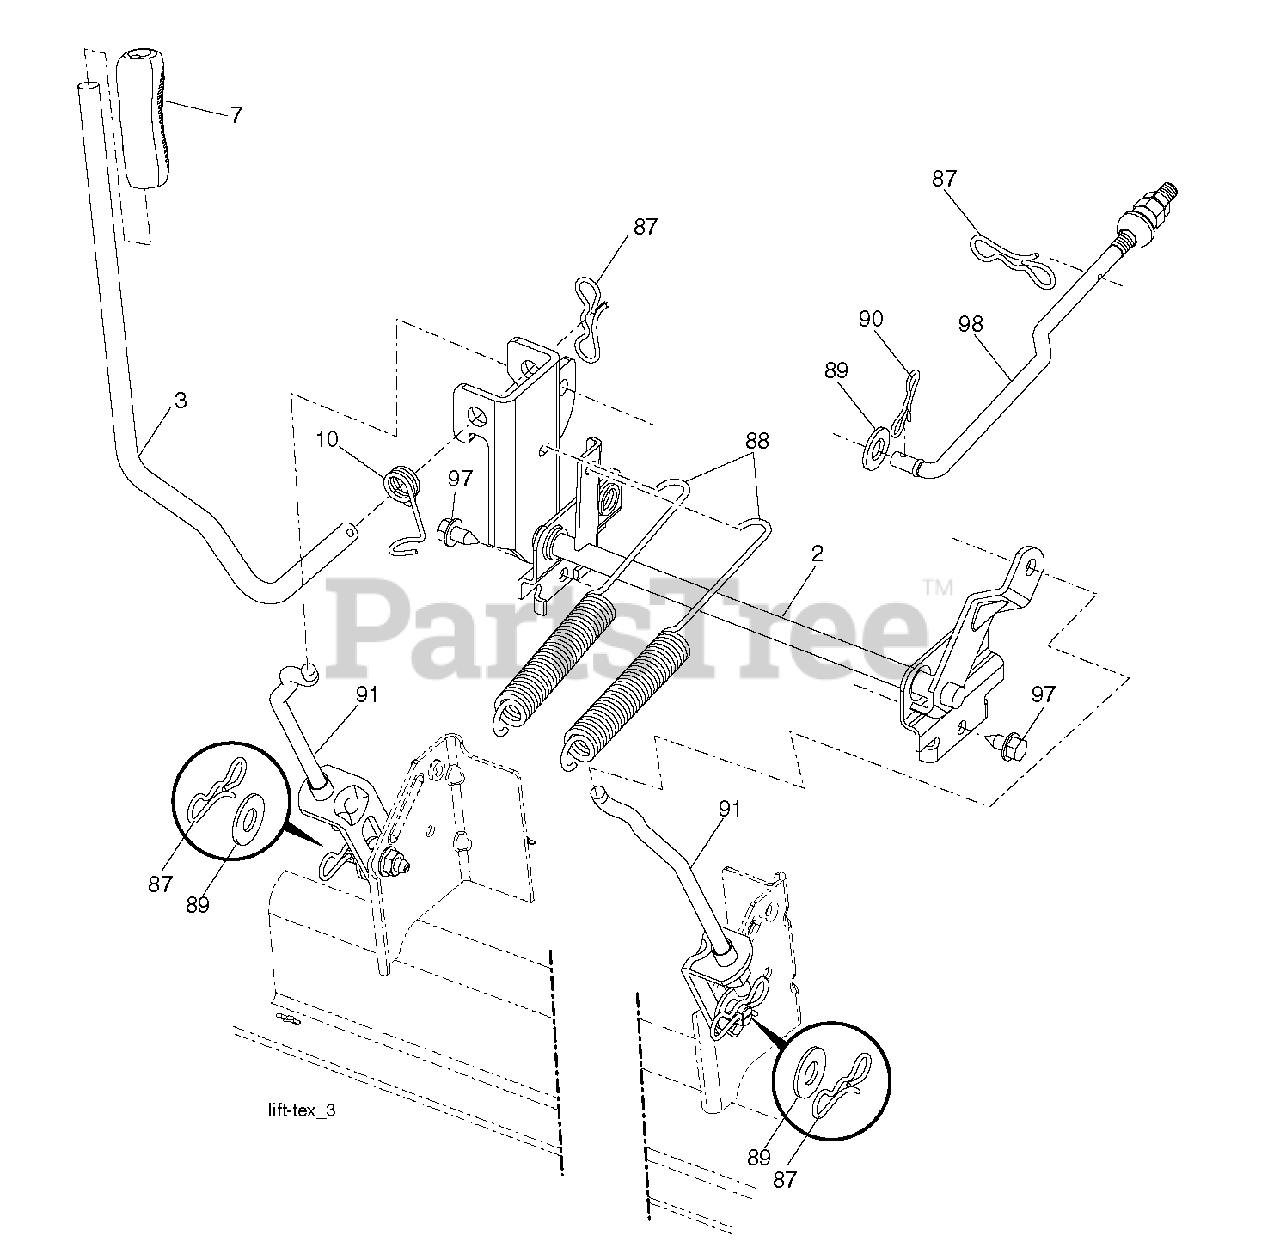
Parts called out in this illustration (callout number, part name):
2	SHAFT.ASM.CROSS.LIFT
3	LEVER.LIFT.HANDLE.LT
10	SPRING.TORSION.LIFT.HA
87	PIN.COTTER.7/16.BOW TI
88	SRPING.LIFT.ASSIST
89	WASHER.CLEAR.ZINC
90	PIN.COTTER.5/16.BOW TI
91	LINK.ASM.LIFT.REAR
97	SCREW, 3/8-16X3/4
98	LINK.ASM.SUSP.FRONT.MWR.10.5
